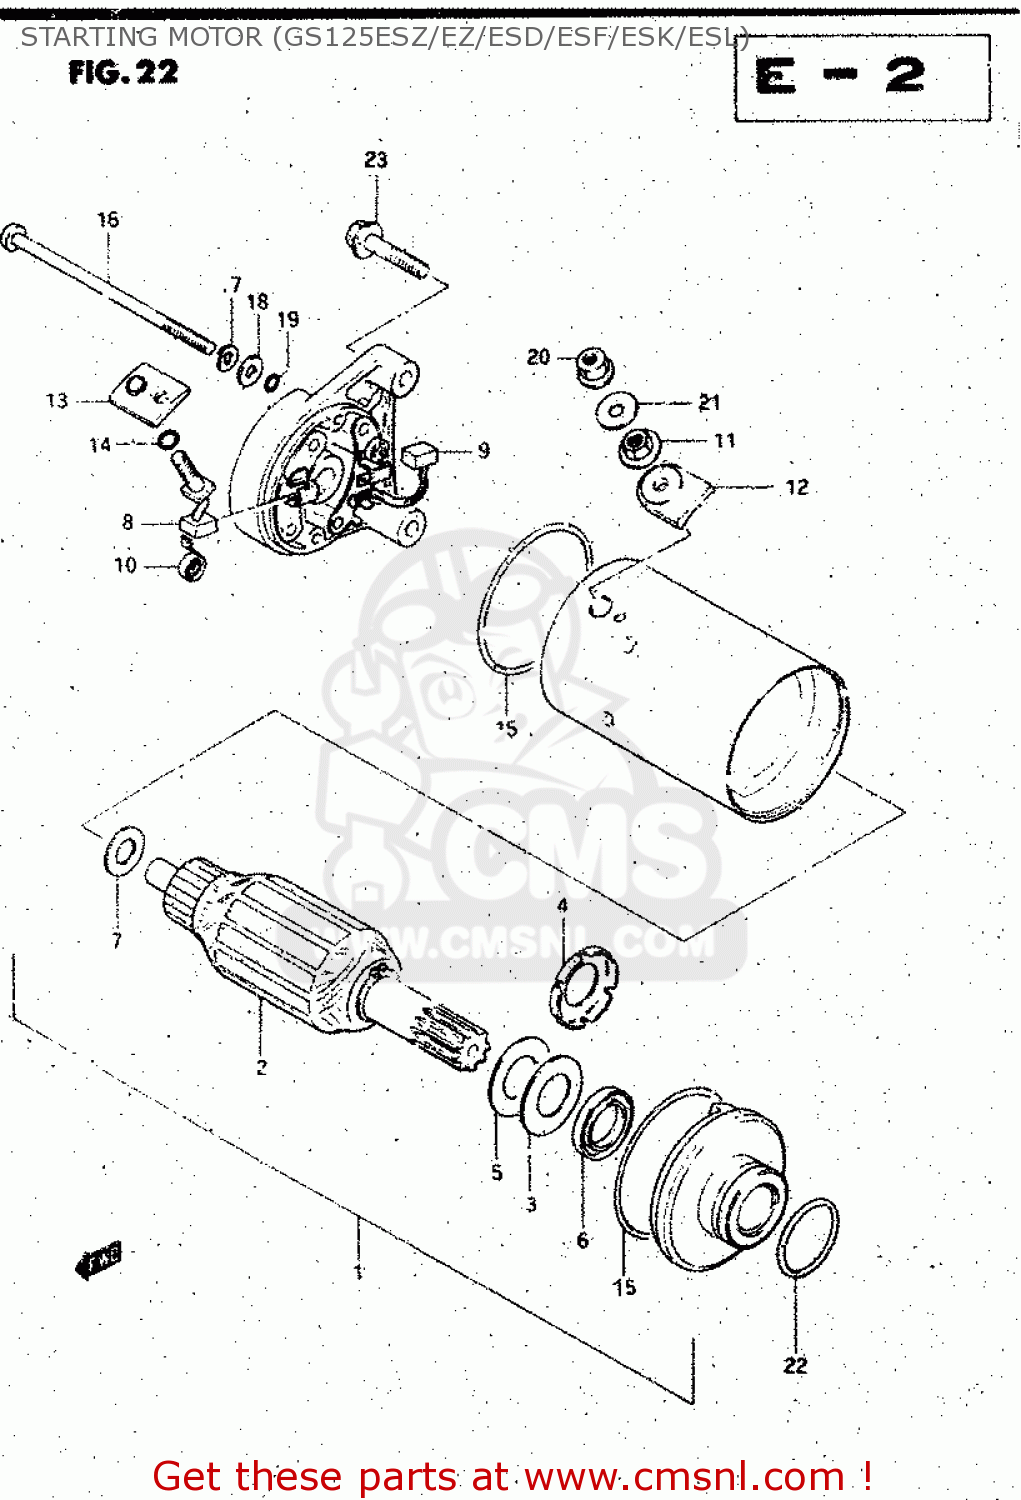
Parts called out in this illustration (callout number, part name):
1	MOTOR ASSEMBLY,STARTING
2	ARMATURE
3	RING,SNAP
4	SHIM,ARMATURE
5	SHIM
6	SEAL,OIL
7	SHIM,ARMATURE
8	BRUSH(+)
9	BRUSH(-)
10	SPRING
11	NUT
12	BUSH,A
13	BUSH,B
14	O RING
15	O-RING
16	BOLT
17	LOCK WASHER
18	WASHER
19	O RING
20	NUT
21	WASHER (6.7X16X1.8)
22	O RING(D:3,ID:24.5)
23	BOLT
